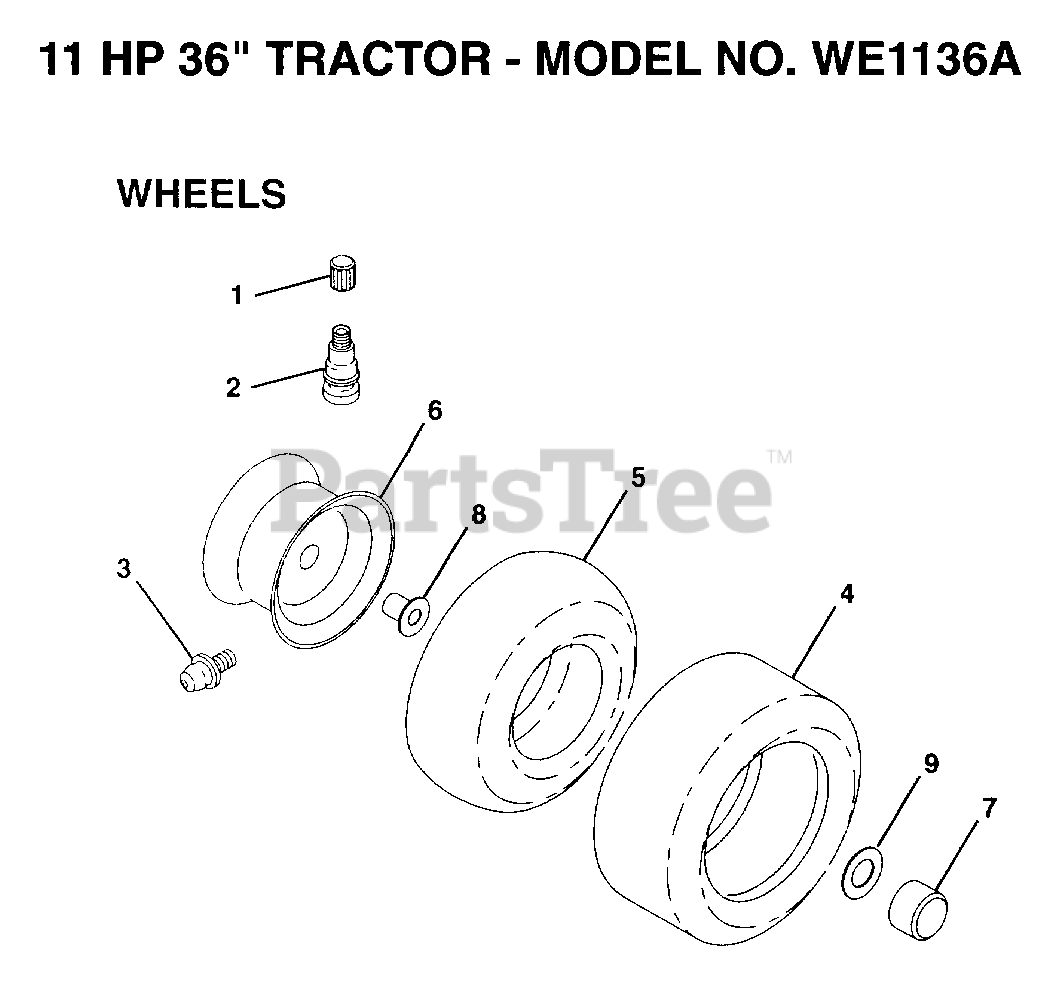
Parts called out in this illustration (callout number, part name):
1	VALVE CAP
2	VALVE STEM LT
3	FITTING LT
4	TIRE
4A	TIRE.16X7.5-8
5	TUBE.5.3/4.5/6
7	HUB CAP
8	"FLANGE, BEARING"
9	WASHER
